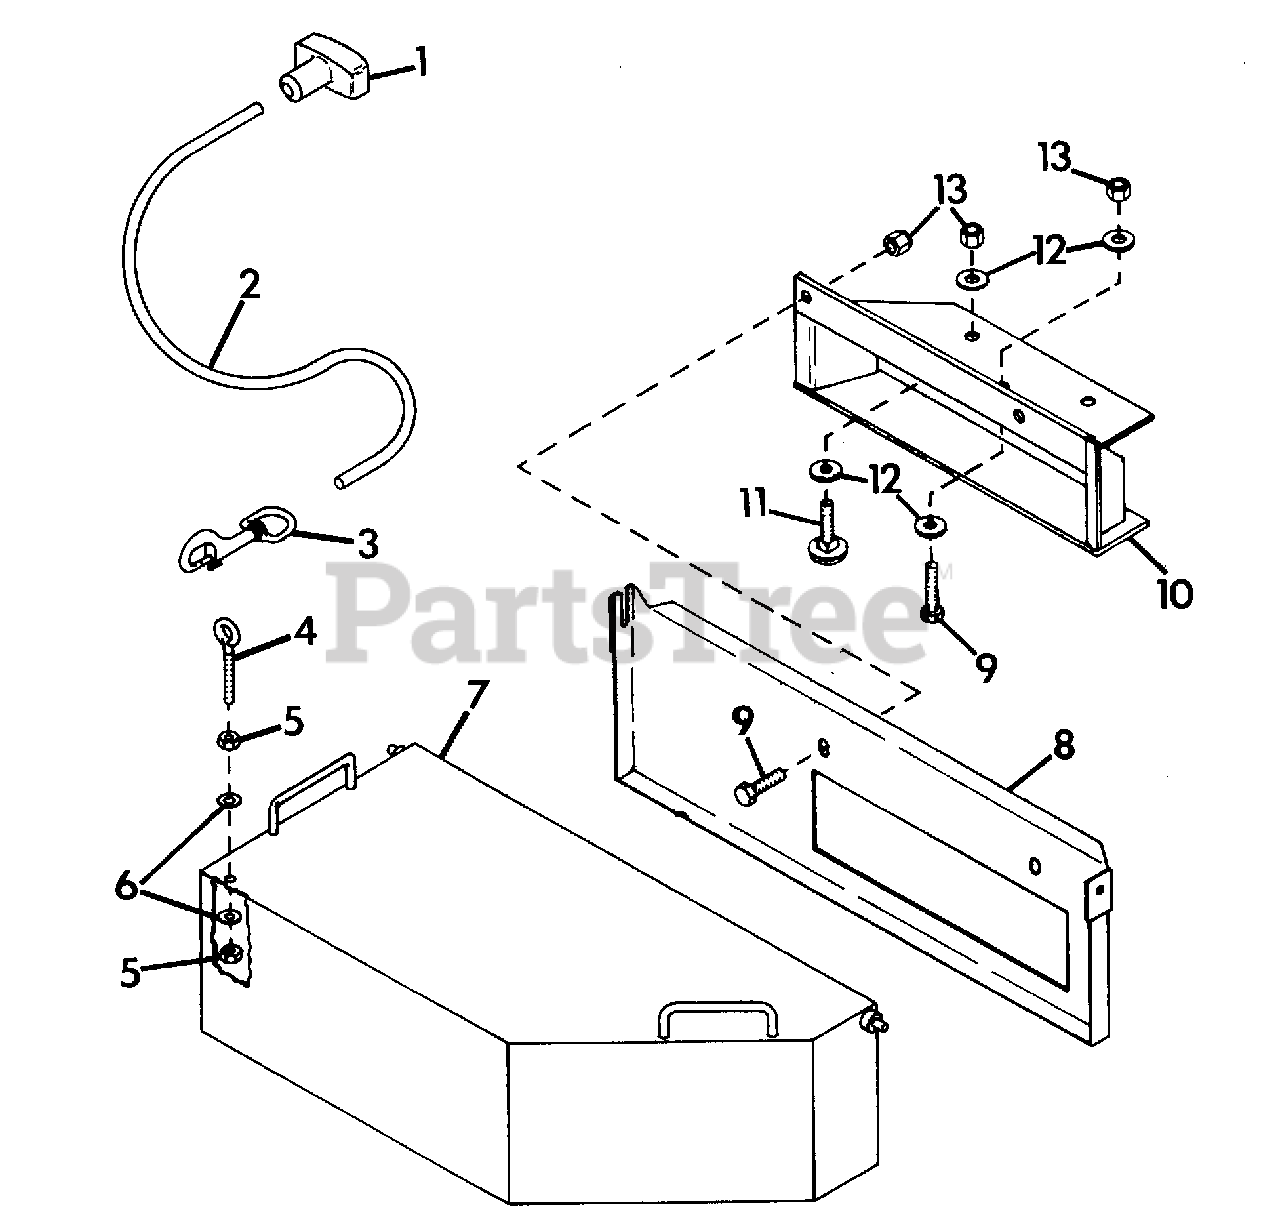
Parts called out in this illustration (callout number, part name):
1	HANDLE
2	ROPE, #6 66"
3	SNAP, SWIVEL
4	BOLT, EYE
5	NUT, HEX 5/16-18
6	WASHER, FLAT .312X.734X.065
7	WELDMENT, GRASS CATCHER
8	WELDMENT, SUPPORT FRAME
9	BOLT, HEX 3/8-16X1.00
10	WELDMENT, CHUTE ADAPTOR
11	BOLT, 3/8-16X1.00 RD HD SQ NK
12	WASHER, FLAT .406X.812X.065
13	NUT, LOCK 3/8-16
